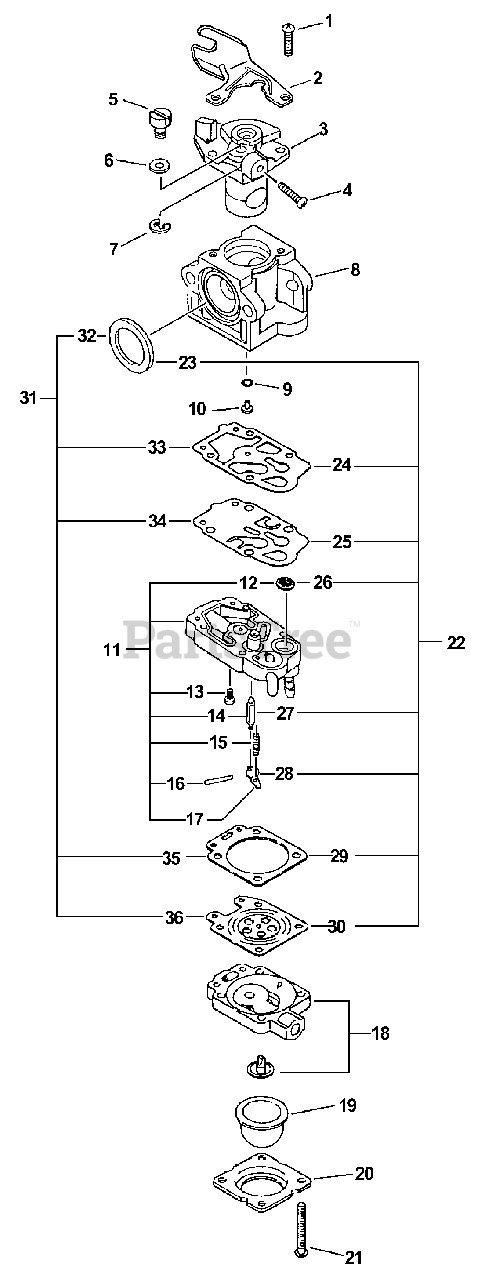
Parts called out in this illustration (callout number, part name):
2	BRACKET, CABLE
3	THROTTLE VALVE ASSY
4	SCREW, IDLE ADJUST
7	RING, RETAINING
8	BODY, CARBURETOR
11	BASE, PURGE
12	STRAINER
13	SCREW, METERING LEVER PIN
14	VALVE, INLET NEEDLE
15	SPRING, METERING LEVER
16	PIN, METERING LEVER
17	LEVER, METERING
18	PURGE BASE ASSY
19	BULB, PURGE
20	RETAINER, PURGE BULB
21	SCREW, PUMP COVER
22	REPAIR KIT
23	SEAL
24	GASKET, PUMP
25	DIAPHRAGM, PUMP
26	STRAINER
27	VALVE, INLET NEEDLE
28	LEVER, METERING
29	GASKET, DIAPHRAGM
30	DIAPHRAGM, METERING
31	DIAPHRAGM/GASKET KIT
32	SEAL
33	GASKET, PUMP
34	DIAPHRAGM, PUMP
35	GASKET, DIAPHRAGM
36	DIAPHRAGM, METERING
